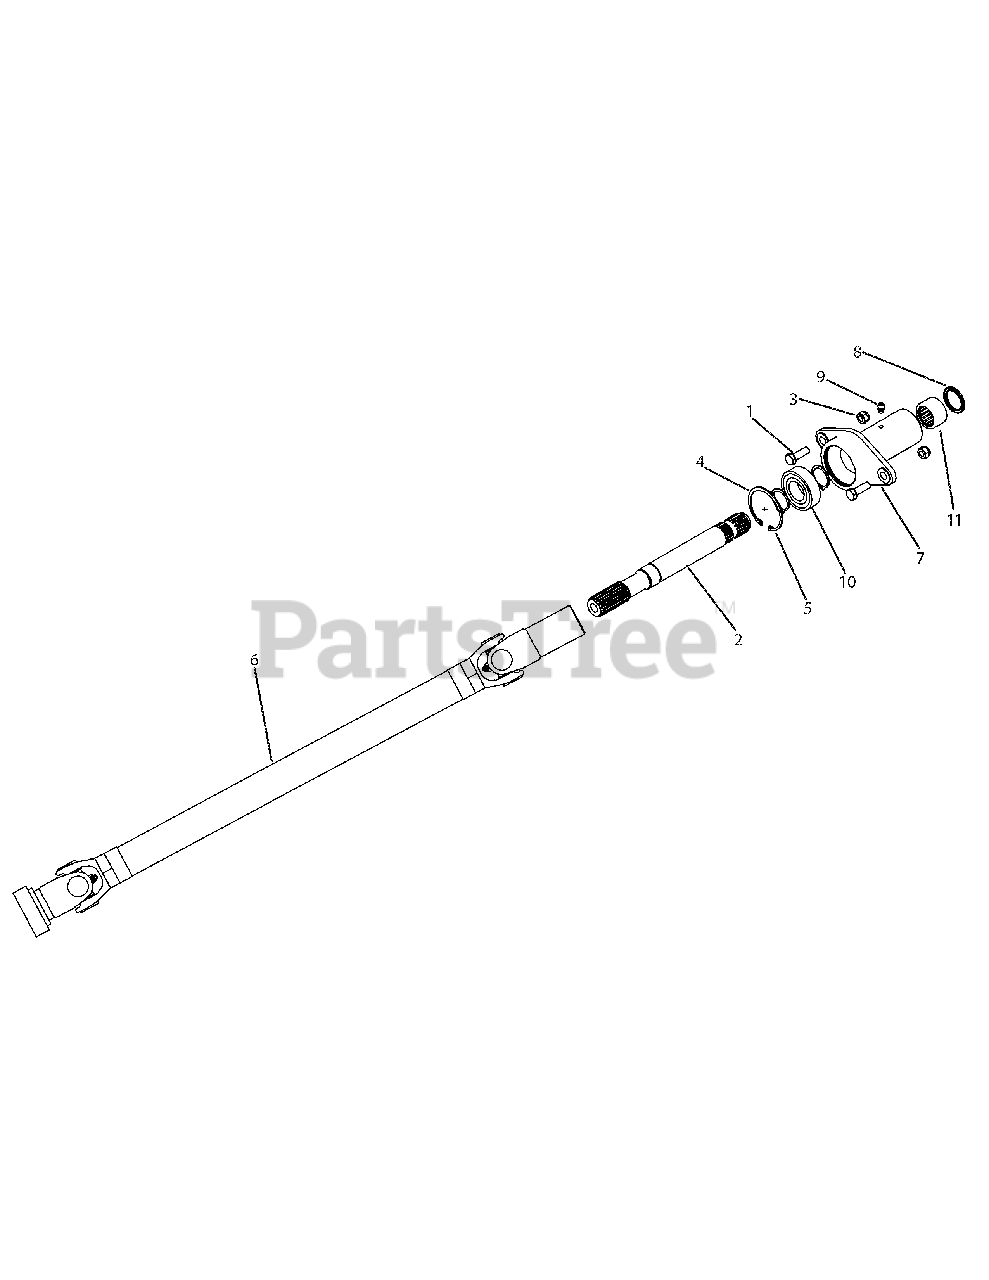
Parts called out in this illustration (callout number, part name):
1	Hex Screw, 5/16-18 x 1.00
2	Spline Shaft
3	Hex Lock Nut, 5/16-18
4	Shaft Snap Ring
5	Retainer Ring
6	Repair Kit, Yoke Lock
7	Shaft
8	Grease Seal, 1.31 x 1.00
9	Lube Fitting
10	Ball Bearing, 1.00 ID x 2.00 OD
11	Bearing, 1.000 x 1.3125 x .7500
